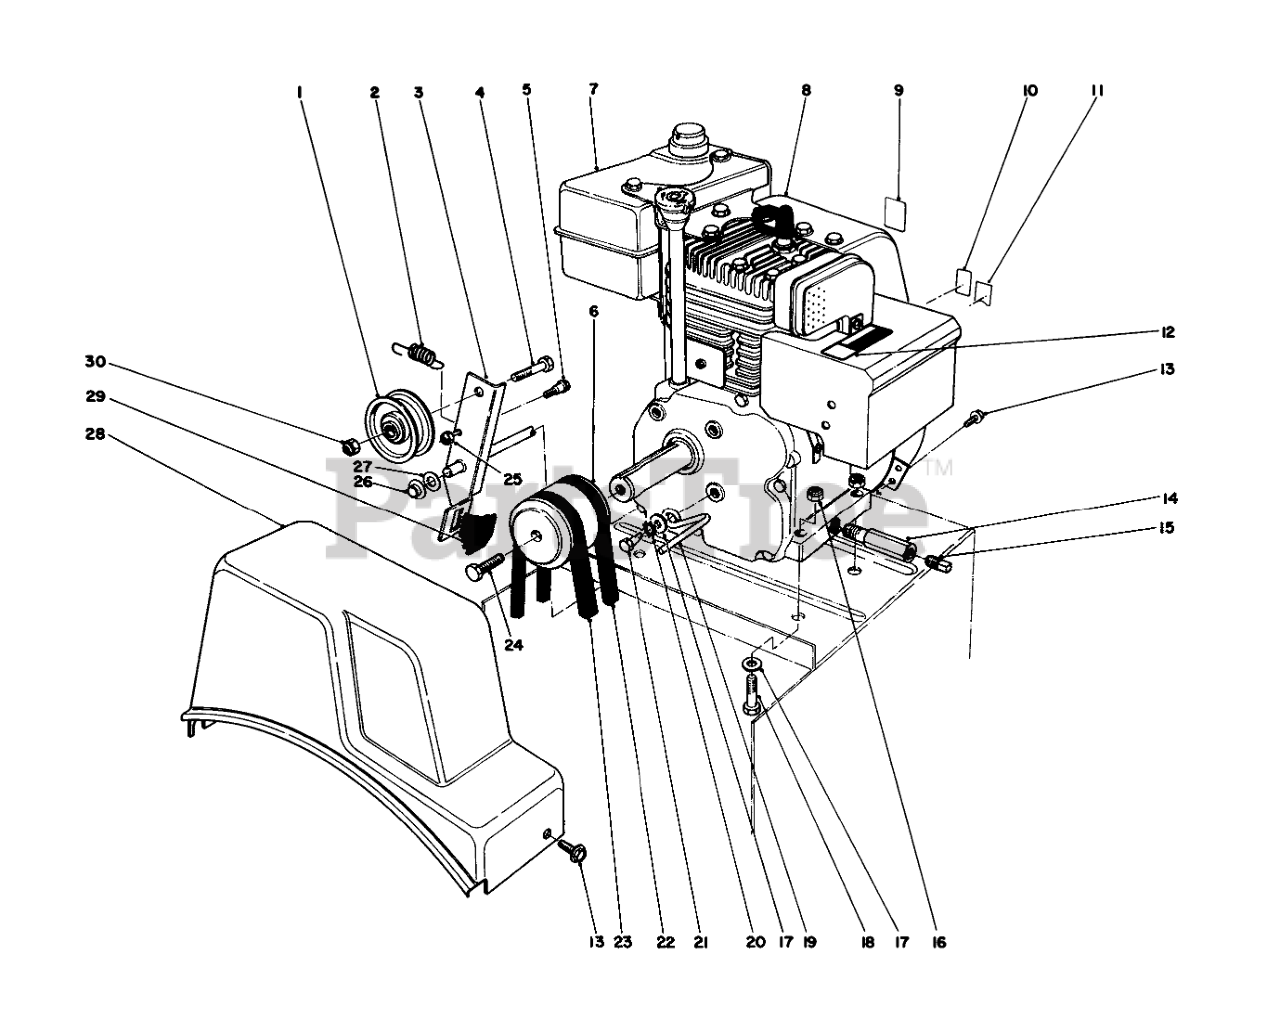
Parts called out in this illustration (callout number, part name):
1	Idler Pulley
2	SPRING
3	Auger Clutch (Incl. Ref. #29)
4	SCREW-HH
5	BOLT-SHOULDER
6	PULLEY-ENGINE
7	GAS TANK 2 QT W CAP
8	Engine
9	PRIMER DECAL
10	DECAL THROTTLE
11	CHOKE DECAL
12	HOT SURFACE DECAL
13	SCREW-HWH
14	PIPE-NIPPLE
15	CAP-PIPE
16	NUT-LOCK, NI
17	WASHER-PLAIN
18	SCREW-HH
19	RETAINER-BELT
20	WASHER-LOCK
21	SCREW-HH
22	V BELT-3L, TRACTION
23	V-BELT (29.50 INCH)
24	SCREW-SPECIAL
25	NUT-LOCK, CONE
26	RETAINER-PUSH ON
27	WASHER-FLAT
28	COVER-BELT
29	Brake Pad
30	NUT-LOCK, CONE
